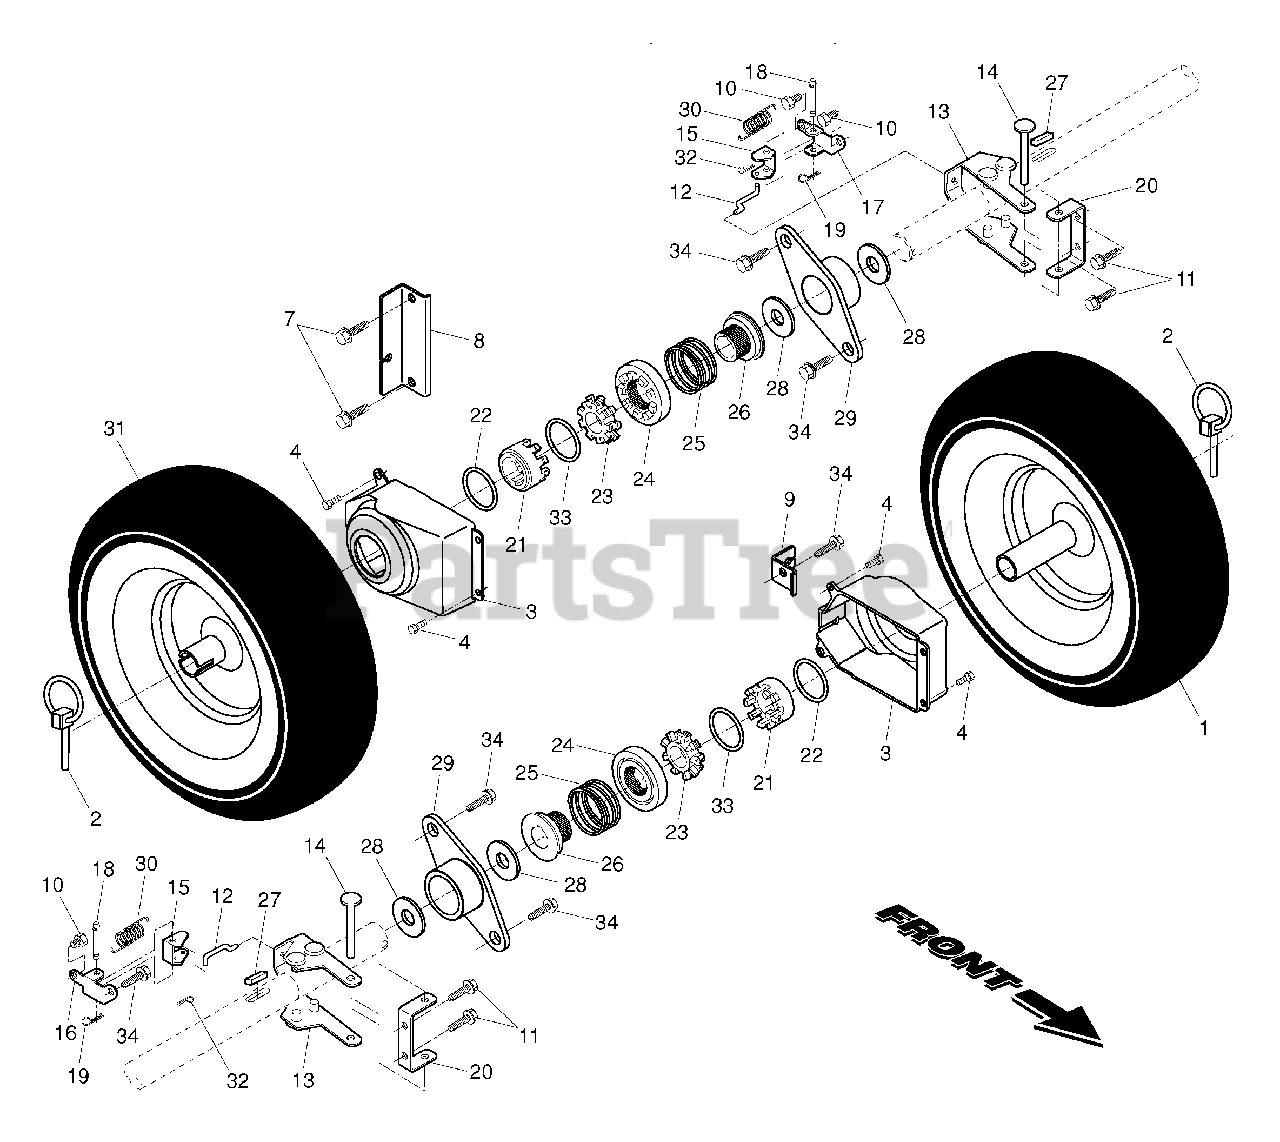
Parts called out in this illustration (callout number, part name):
1	Wheel Assembly, 12", Power Steering, LH
2	Pin, Klik 1/4
3	Cover, Power Steering
4	Bolt, Shoulder #10-24 x 5/8
7	Capscrew, Hex Head, Flanged 3/8-16 x 1
8	Bracket, Steering Cable, RH
9	Bracket, Steering Cable, LH
10	Screw, Hex Head 1/4-20 x 3/8
11	Screw, Hex Head 5/16-18 x 1/2
12	Link, Steering Lever
13	Yoke, Steering
14	Pin, Steering Lever
15	Bellcrank
16	Bracket Assembly, LH Steering
17	Bracket Assembly, RH Steering
18	Pin, Steering Bellcrank
19	Retainer, Hairpin
20	Bracket, Steering
21	Driver, Wheel
22	Ring, Wire Retainer
23	Lobe, Wheel
24	Slide, Clutch
25	Spring, Clutch Slide
26	Lobe, Axle
27	Key, Square
28	Washer, Thrust (1")
29	Bearing, Axle
30	Spring, Return
31	Wheel Assembly, 12", Power Steering, RH
32	Clip, Retainer
33	Ring, Retaining
34	Screw, Hex Head 5/16-18 x 5/8
